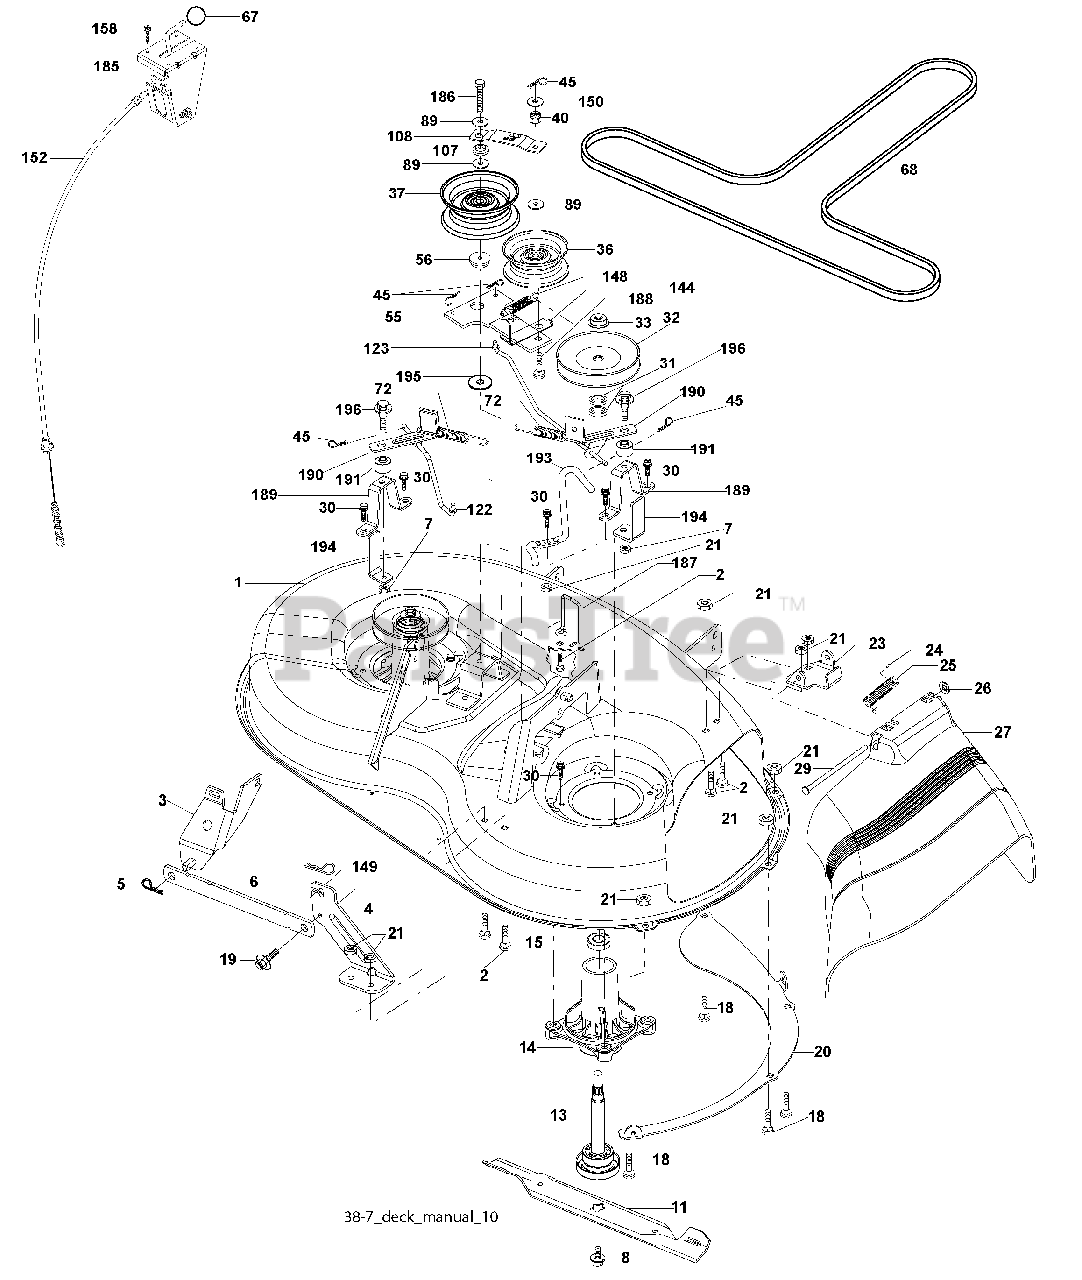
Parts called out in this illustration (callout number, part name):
1	Mower Housing Assembly
2	Bolt Carriage 5/16-18 x 3/4
3	Bracket Asm Fr. Sway Bar
4	Bracket Deck Sway Bar 38"/42"
5	Retainer Spring
6	Bar Sway Deck
7	Nut Lock 5/16-18 UNC
8	Bolt 3/8-24 x 1.25 Gr. 8
11	Blade Mower 38" High PERF
11	Blade 38" 3 in 1 Premium
13	Shaft Assembly, Mandrel, Vented
14	Housing, Mandrel, Vented
15	Bearing, Ball, Mandrel
18	Blade Rdhd Sqnk 5/16-18 x 5/8
19	Bolt, Shoulder
20	Baffle Vortex Front
21	Nut
23	Bracket, Mower Deflector
24	Cap, Sleeve
25	Spring, Torsion, Deflector
26	Nut, Push
27	Shield, Deflector
29	Rod, Hinge
30	Screw Thdrol.
31	Washer, Spacer
32	Pulley, Mandrel
33	Nut, Toplock
36	Pulley, Idler, Flat
37	Pulley, Idler Flat
40	Nut, Crownlock 3/8-16 unc
45	Retainer
55	Idler Arm Assembly
56	Spacer, Retainer
67	Knob
68	V-Belt
72	Spring Brake Return
89	Washer 13/32 x 13/16 x 11 Ga.
107	Spacer Retainer
108	Stiffener, Idler Arm
122	Rod, Brake LH
123	Rod, Brake RH
144	Keeper Belt Idler Tension
148	Spring Return Idler
149	Retainer Spring Yellow
150	Washer 9/32 x 3/4 x 10 Ga.
152	Clutch Cable 38"
158	Screw Hex Thd Cut 1/4-20 x 1/2
185	Head Asm Cable Clutch
186	Screw Hex Wsh Thdrol 3/8-16 x 2-3/4
187	Keeper Belt M Shape
188	Bolt Carriage Idler
189	Brake Stand
190	Brake Arm
191	Brake Spacer
193	Keeper Belt Rh Mandrel
194	Brake Guard
195	Washer 13/32 x 2 x 10 Ga.
196	Bolt/Washer Asm. 5/16-18
196	Brake Assembly
196	Mandrel Assembly
196	Replacement Mower, Complete
